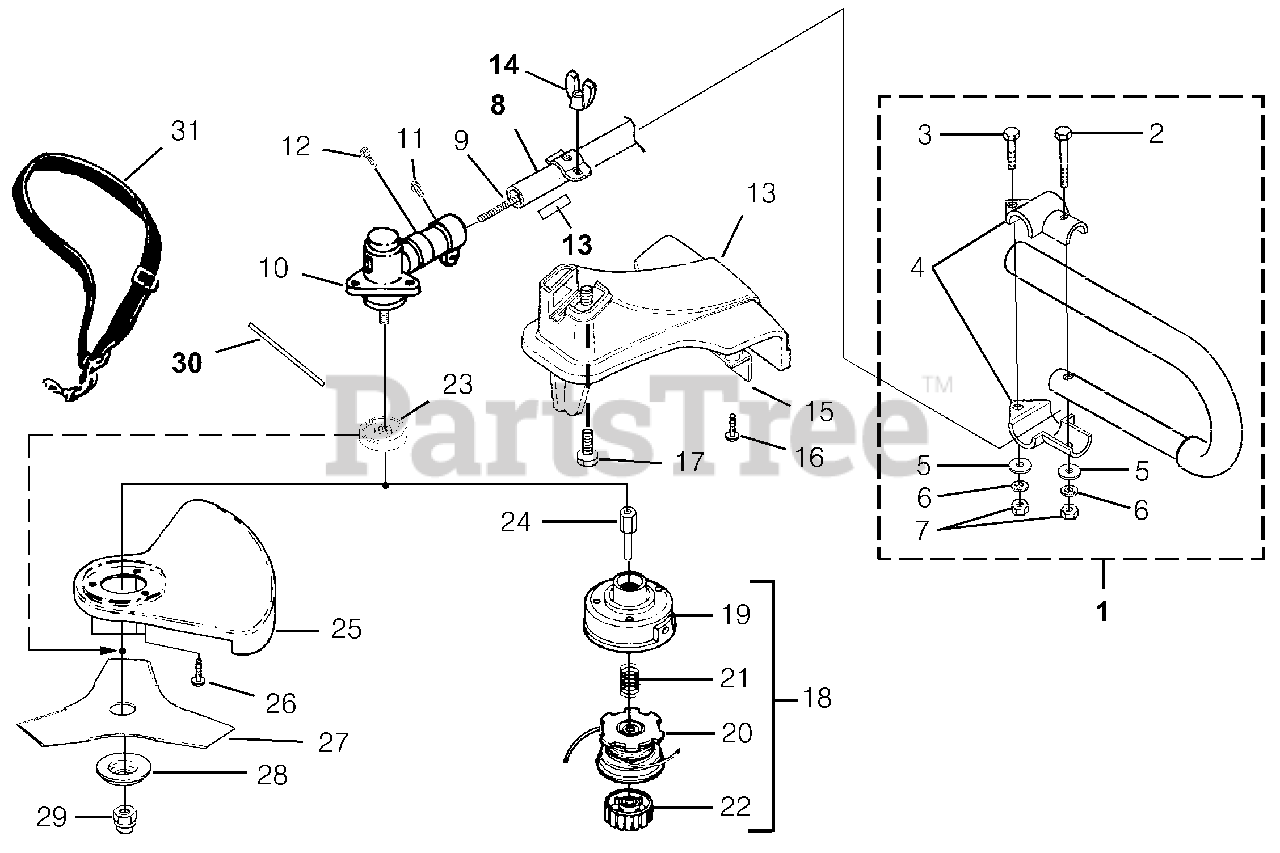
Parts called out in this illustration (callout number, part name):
1	HANDLE("J")
2	SCREW-Hex Hd. (1/4-20 X 1 1/2")
3	SCREW-Hex Hd. (1/4-20 X 1")
4	CLAMP-Handle Bar
5	WASHER-Flat (1/4")
6	WASHER-Lock (1/4")
7	NUT-Hex (1/4-20)
8	DRIVESHAFT HOUSING
9	FLEXSHAFT
10	GEAR HEAD
11	Screw, Cap Hd. (1/4-20 X 7/8")
12	Screw-Hex Hd. (10-24 x 1/2")
13	GRASS DEFLECTOR KIT
14	WING NUT
15	BLADE-Cut-Off
16	SCREW, Thread Form. (10-24 X 3/4")
17	SCREW-Square Head
18	STRINGHEAD-Complete (.080")
19	HOUSING & EYELET (Dual Line)
20	SPOOL & STRING (.080")
21	SPRING-Compression
22	RETAINER-Spool (L.H. Thread, Red)
23	WASHER-Flanged
24	ADAPTER-Shaft
25	BLADE GUARD
26	SCREW
27	BLADE-Tri-Arc(TM)
28	WASHER-Cupped (Lower)
29	NUT-Hex (L.H.)
30	TOOL-Holding Pin
31	HARNESS
